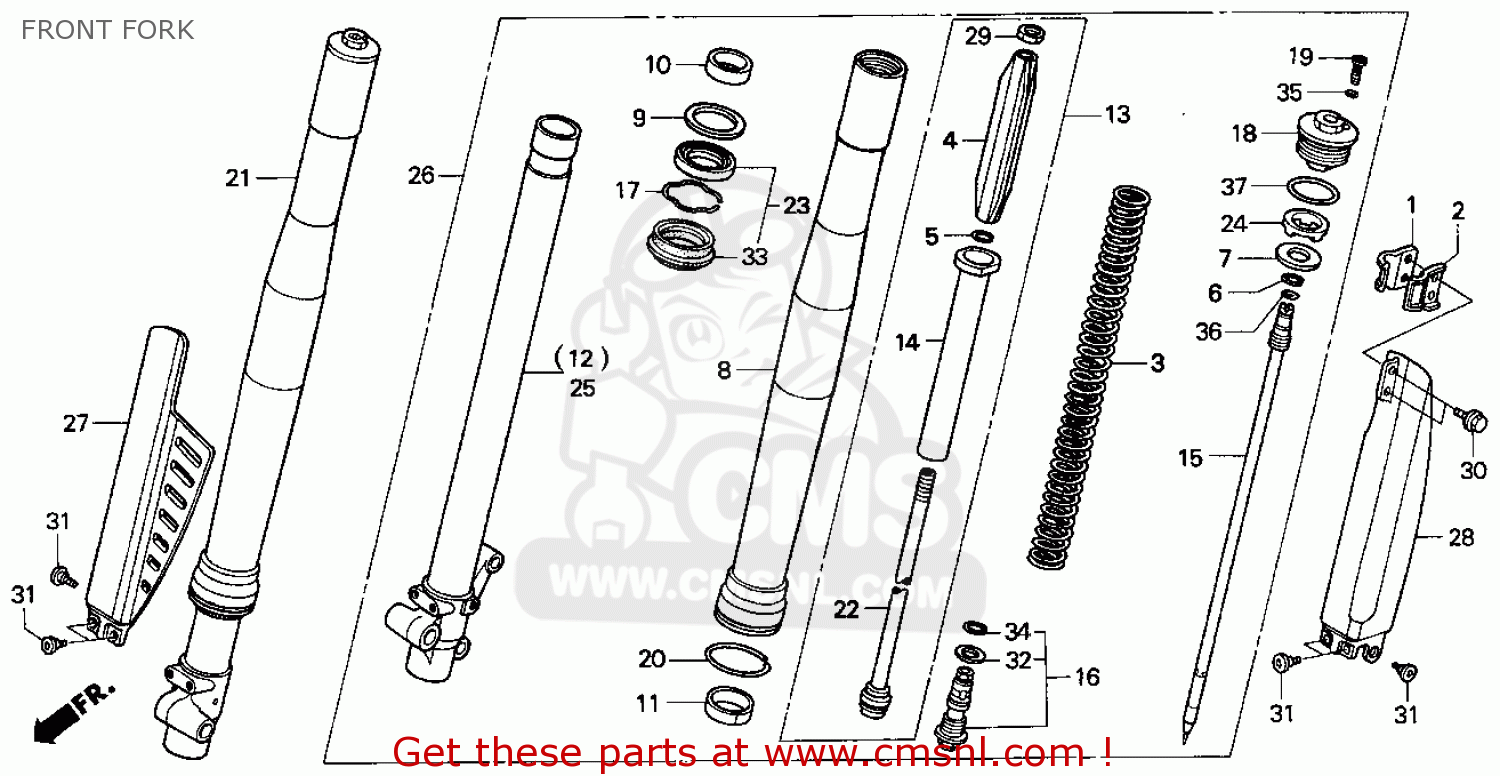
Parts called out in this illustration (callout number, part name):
1	CLAMPER A,BRK.
2	CLAMPER B,BRK.
3	SPRING,FR FORK (0
4	GUIDE,SPRING
5	RING,STOPPER
6	RING,STOPPER
7	SEAT,SPRING
8	TUBE,OUTER
9	RING,BACK UP
10	BUSH,GUIDE
11	BUSH,SLIDE
12	PIPE COMP,R SLIDE
13	DAMPER COMP,FR
14	DAMPER SUB COMP,F
15	NEEDLE COMP,REBOU
16	BOLT COMP,CENTER
17	RING,OIL SEAT STO
18	BOLT,FR FORK
19	BOLT,PLUG (SHOWA)
20	RING,WEAR
21	FORK SUB ASSY,R F
22	ROD COMP,PISTON
23	SEAL SET,FR FORK
24	RUBBER,STOPPER
25	PIPE COMP,L SLIDE
26	FORK SUB ASSY,L F
27	PROTECTOR,*R177R*
28	PROTECTOR,*R177R*
29	NUT,HEX
30	BOLT,FLANGE,6MM
31	BOLT,PROTECTOR
32	WASHER,SPECIAL
33	SEAL,DUST
34	O RING,15.5X1.5
35	O-RING,2.8X1.9 (S
36	O-RING
37	O-RING,37.2X2.4
